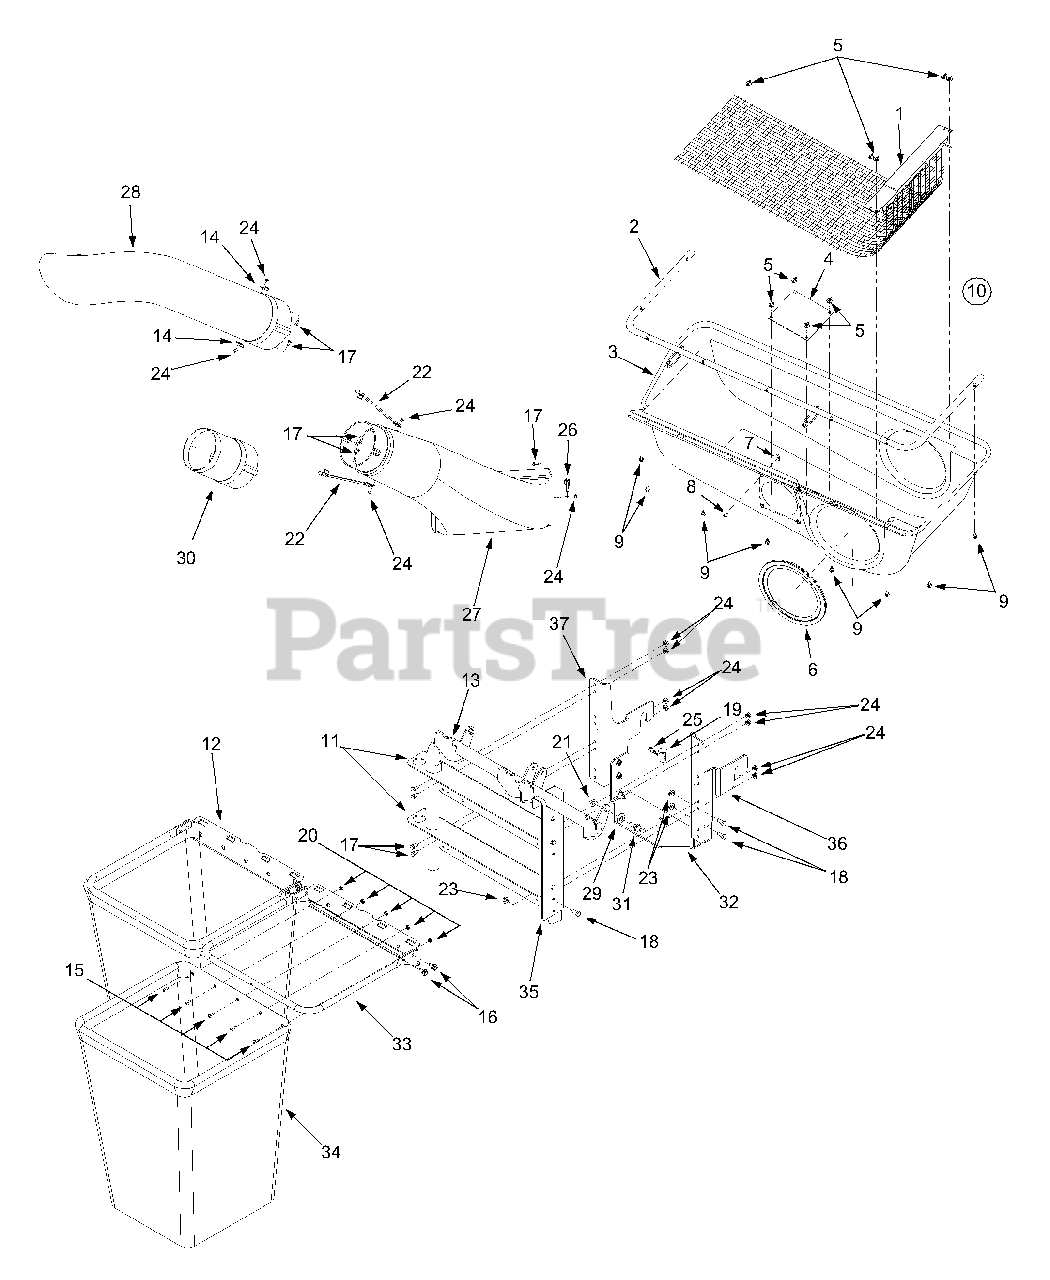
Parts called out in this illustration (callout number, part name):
3	Grass Catcher Cover
4	Plastic Plate, 1/8 x 5.6 sq.
5	Zip Twist Fastener
6	Tube Seal
7	U-Type Speed Nut, #10-24
8	Screw, #10-16 x .5
9	Hex Screw, 1/4-20 x .5
10	Cover Assembly
14	Retainer Hook Bracket
15	Screw, #10-24 x .5
16	Self Tapping Screw, 5/16-18 x .625
17	Hex Cap Screw, 1/4-20 x .62
18	Hex Cap Screw, 5/16-18 x .75
19	Clevis Pin
20	Hex Sems Nut, 10-24
21	Hex Flange Lock Nut, 3/8-16
22	Retainer Strap Assembly
23	Hex Flange Lock Nut, 5/16-18
24	Hex Flange Lock Nut, 1/4-20
25	Internal Cotter Pin, .148 x 3
26	Retainer Strap Assembly
27	Discharge Chute
28	Chute Tube
29	Bell Washer
30	Extension Tube
31	Shoulder Screw, .50 x .27, 3/8-16
34	Bag
